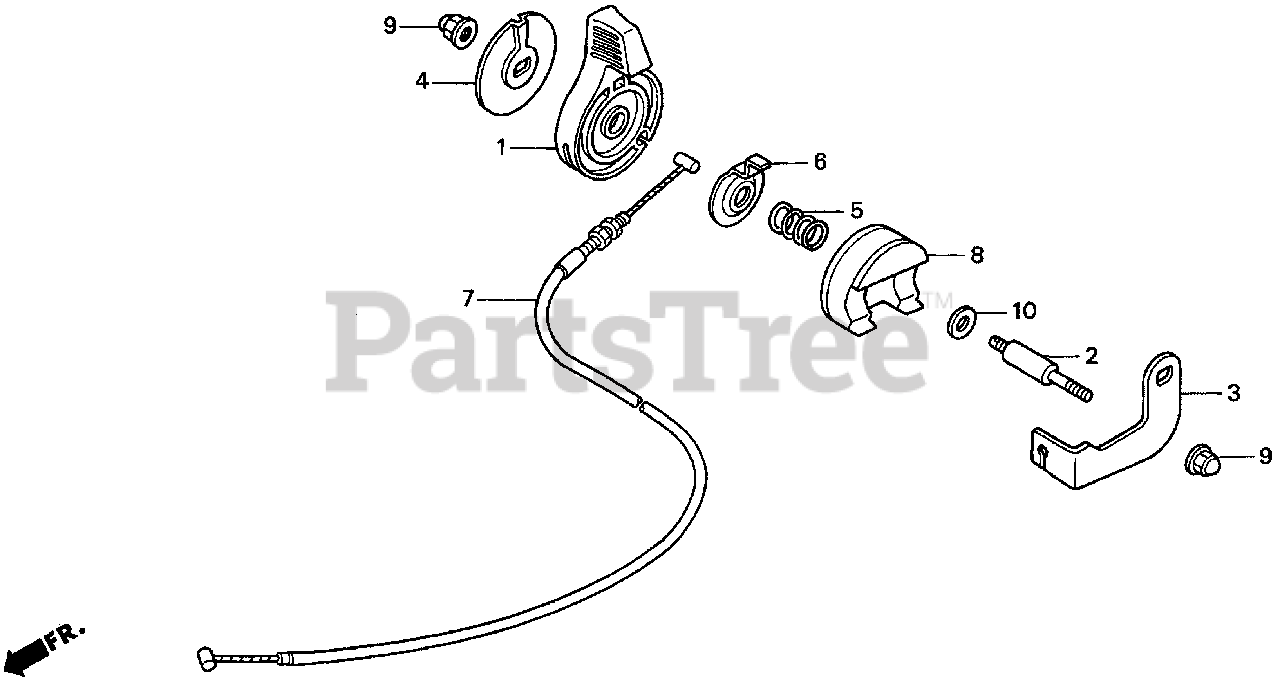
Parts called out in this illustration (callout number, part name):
1	LEVER, THROTTLE
2	PIN, THROTTLE LEVER
3	STAY, THROTTLE CABLE
4	PLATE, THROTTLE LEVER
5	SPRING, THROTTLE LEVER
6	SEAT, SPRING
7	CABLE, THROTTLE
8	COVER, CONTROL
9	NUT, CAP (6MM)
10	WASHER, DRAIN PLUG (12MM)
